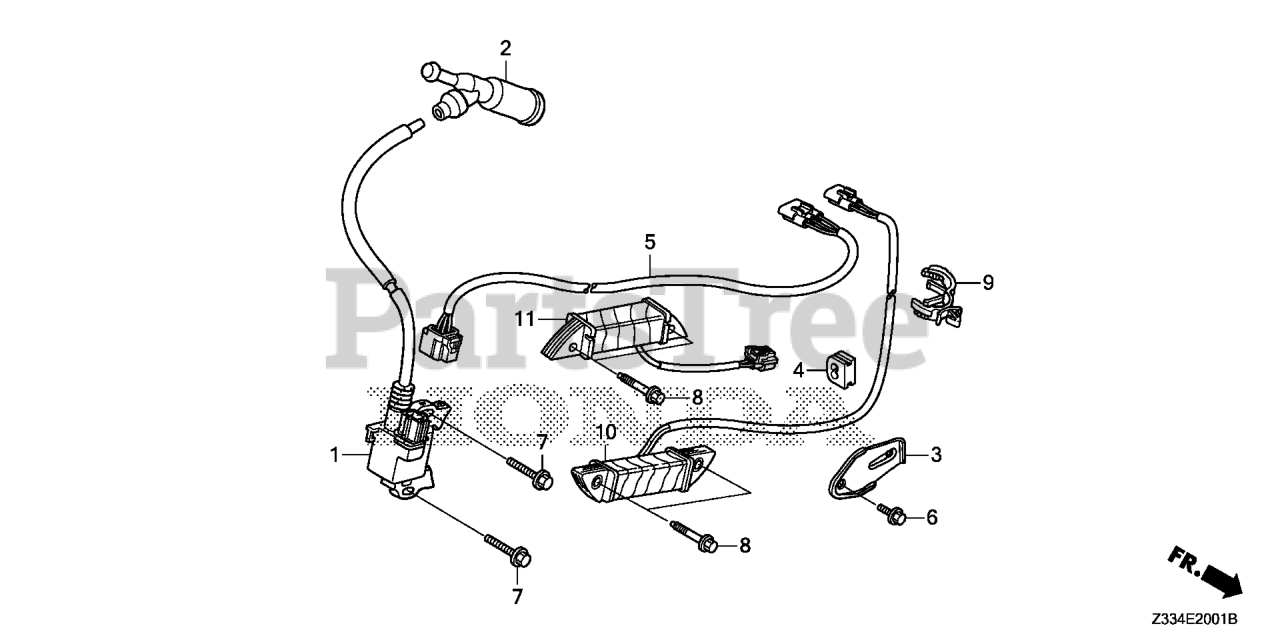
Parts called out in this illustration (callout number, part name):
1	COIL ASSY., IGNITION
2	CAP ASSY., NOISE SUPPRESSOR (NGK Y-EZD)
3	CLAMP, WIRE
4	GROMMET, WIRE
5	WIRE HARNESS ASSY., ENGINE
6	BOLT, FLANGE (6X12) (CT200)
7	BOLT, FLANGE (6X28) (CT200) Use up to Engine SN 1530314.
8	BOLT, FLANGE (6X25) Use up to Engine SN 2056819.
9	CLIP, WIRE HARNESS
10	COIL ASSY., POWER
11	COIL ASSY., POWER (CO)
